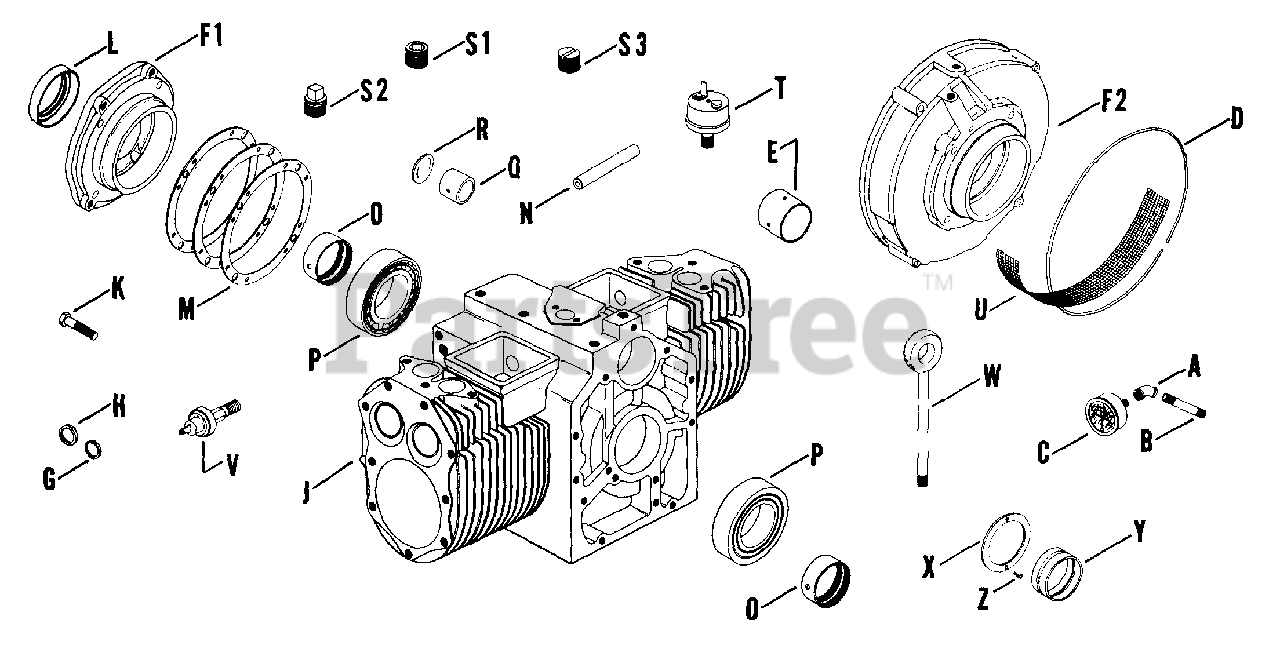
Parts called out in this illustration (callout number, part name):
E	BUSHING - DISCONTINUED
G	INSERT - DISCONTINUED
J	Block, cylinder - assembly (Discontinued--Not Available) (Includes E,G,N & Q)
K	BOLT, HEX CAP USE 25 086 116-S
L	SEAL - DISCONTINUED
M	GASKET - DISCONTINUED
N	GUIDE - DISCONTINUED
M	GUIDE - DISCONTINUED
O	SLEEVE - DISCONTINUED
O	SLEEVE .010 - DISCONTINUED
P	BEARING - DISCONTINUED
Q	BUSHING - DISCONTINUED
S2	PLUG, PIPE USE 25 139 52-S
X	Washer, thrust (Discontinued--Not Available)
Y	Bushing, main bearing (Discontinued--Not Available)
